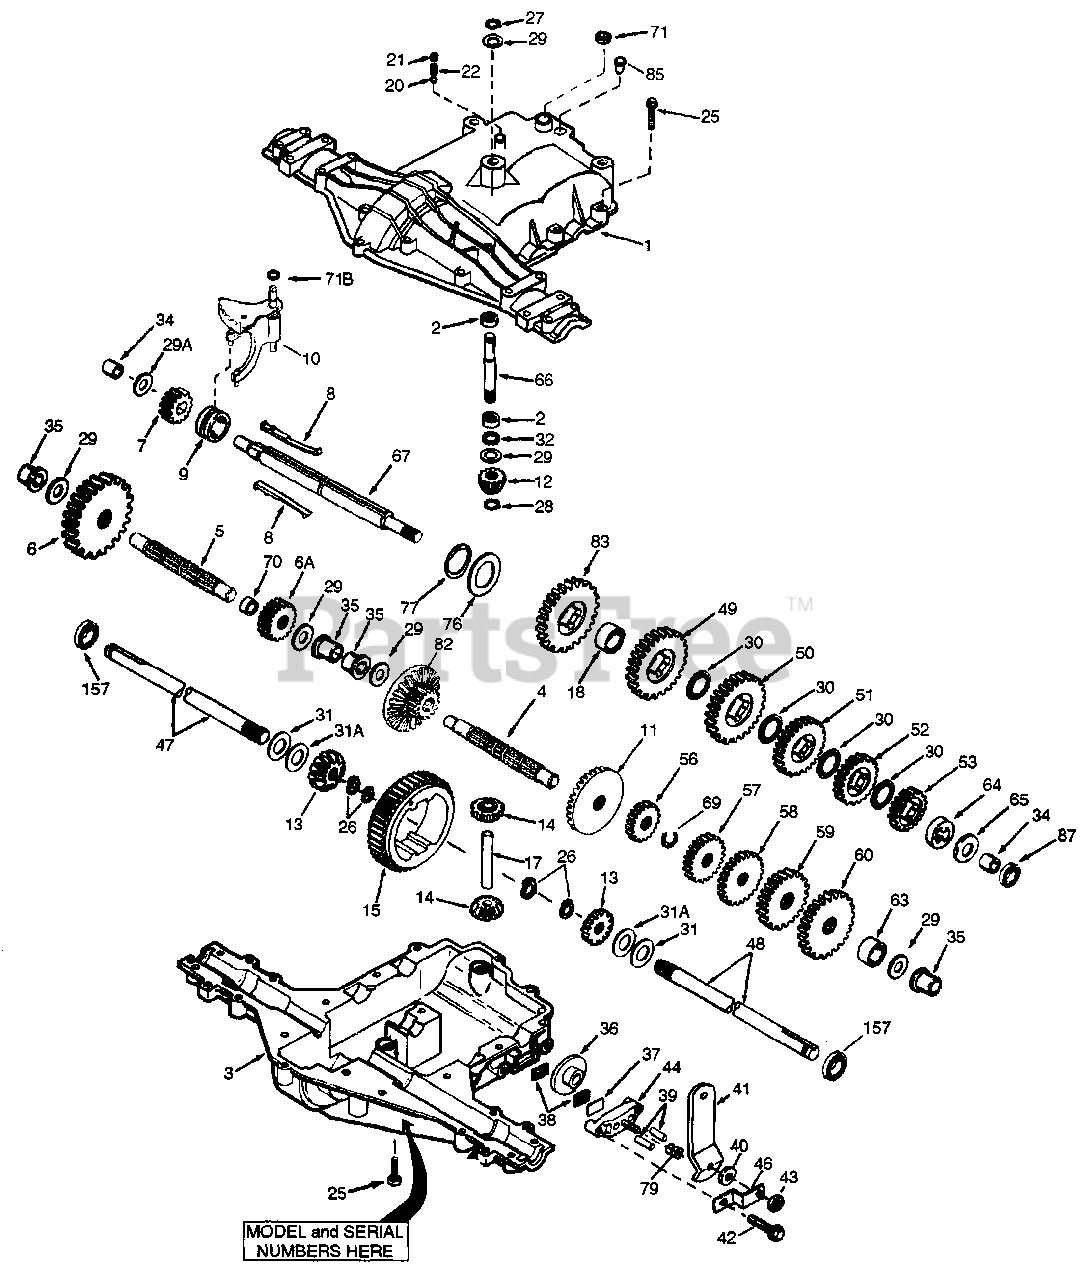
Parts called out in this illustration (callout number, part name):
1	Transaxle Cover
2	Needle Bearing
3	Transaxle Case
4	Countershaft
5	Output Shaft
6	Spur Gear
6A	Spur Gear
7	Spur Gear
8	Shift Key
9	Shift Collar
10	Shift Rod & Fork
11	Bevel Gear
12	Input Bevel Pinion
13	Bevel Gear
14	Bevel Pinion
15	Ring Gear
20	Ball 5/16 diameter
21	Set Screw 3/8-16 x 3/8
25	Screw 1/4-20 x 1-1/4
26	Retaining Ring
27	Retaining Ring
28	Retaining Ring
31	Washer
31A	Flat Washer
32	Oil Seal 5/8
35	Flanged Bushing
36	Brake Disk
37	Brake Pad Plate
38	Brake Pad
40	Washer
41	Brake Lever
42	Screw 1/4-20 x 1-1/4
43	Locknut 5/16-24
44	Brake Pad Holder
46	Brake Lever Bracket
47	Axle
48	Axle
49	Spur Gear
50	Spur Gear
51	Spur Gear
52	Spur Gear
53	Spur Gear
56	Spur Gear
57	Spur Gear
58	Spur Gear
59	Spur Gear
60	Spur Gear
63	Countershaft Spacer 1-1/8 x 3/8
64	Brake Shaft Spacer 1-3/8 x 3/8
66	Input Shaft
67	Shifter & Brake Shaft
69	Retaining Ring
71	Square Cut Ring
77	Inverted Retaining Ring
82	Bevel & Spur Gear
83	Spur Gear
87	Oil Seal 9/16
157	Oil Seal 3/4
